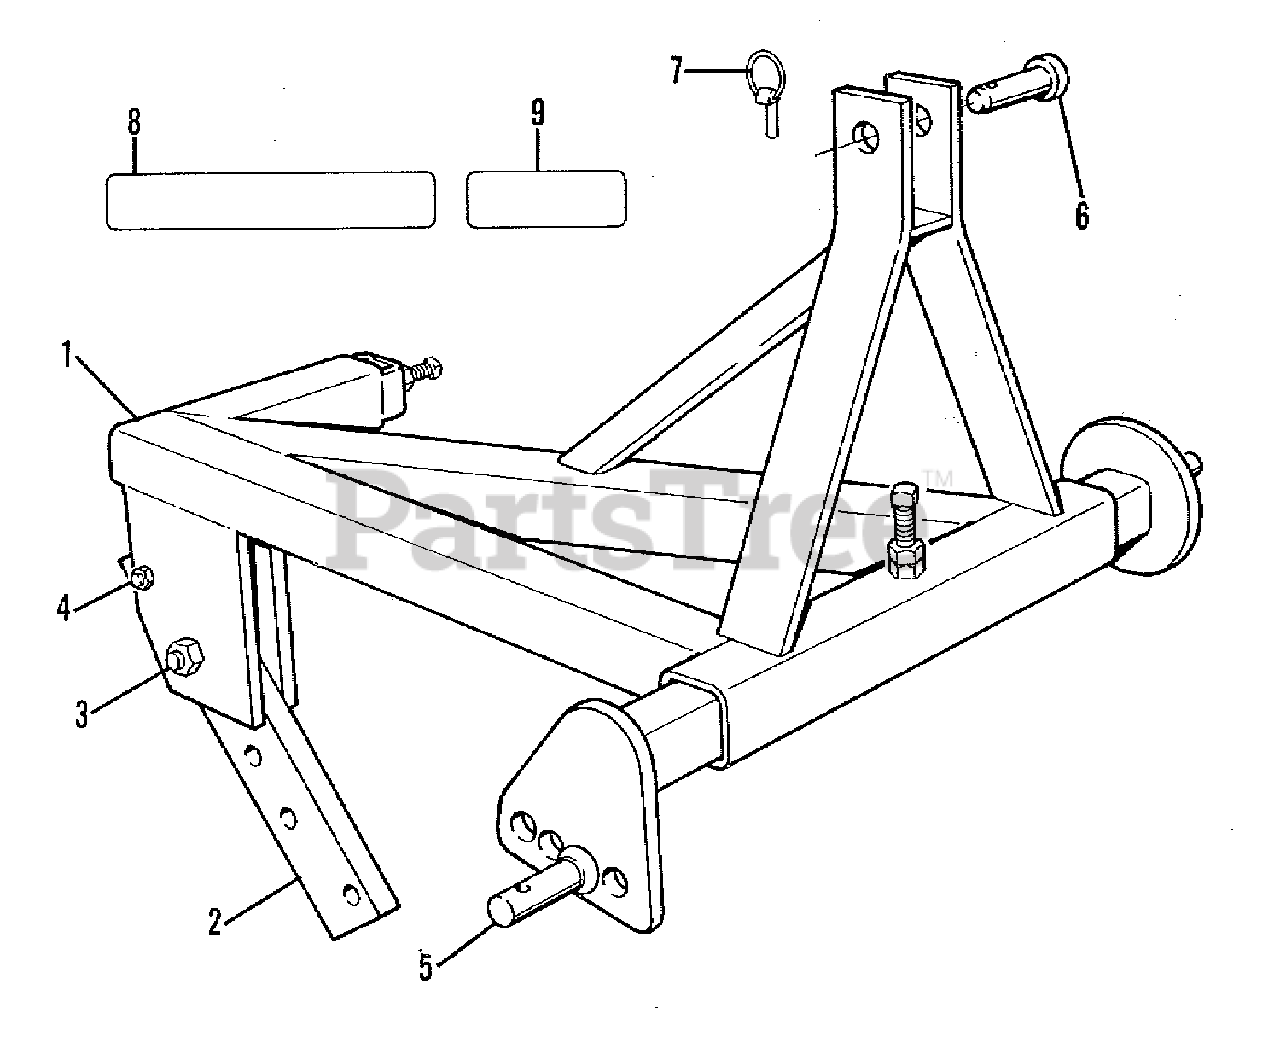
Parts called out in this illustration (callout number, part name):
1	FRAME ASSEMBLY
1	SETSCREW, Square Head, Cup Point, 5/8NC x 1-1/4
2	CAPSCREW, 5/8NC x 3
2	LOCKWASHER, 5/8
3	CAPSCREW, Beam Pivot, 3/4NC x 3
4	CAPSCREW, Beam Shear, 1/2NC x 3
4	LOCKWASHER, 1/2
5	PIN, Link (Cat. l)
5	LCOKWASHER, 7/8
6	PIN, Hitch, Upper
8	DECAL (Allis-Chalmers)
9	DECAL (41 Model Identification)
